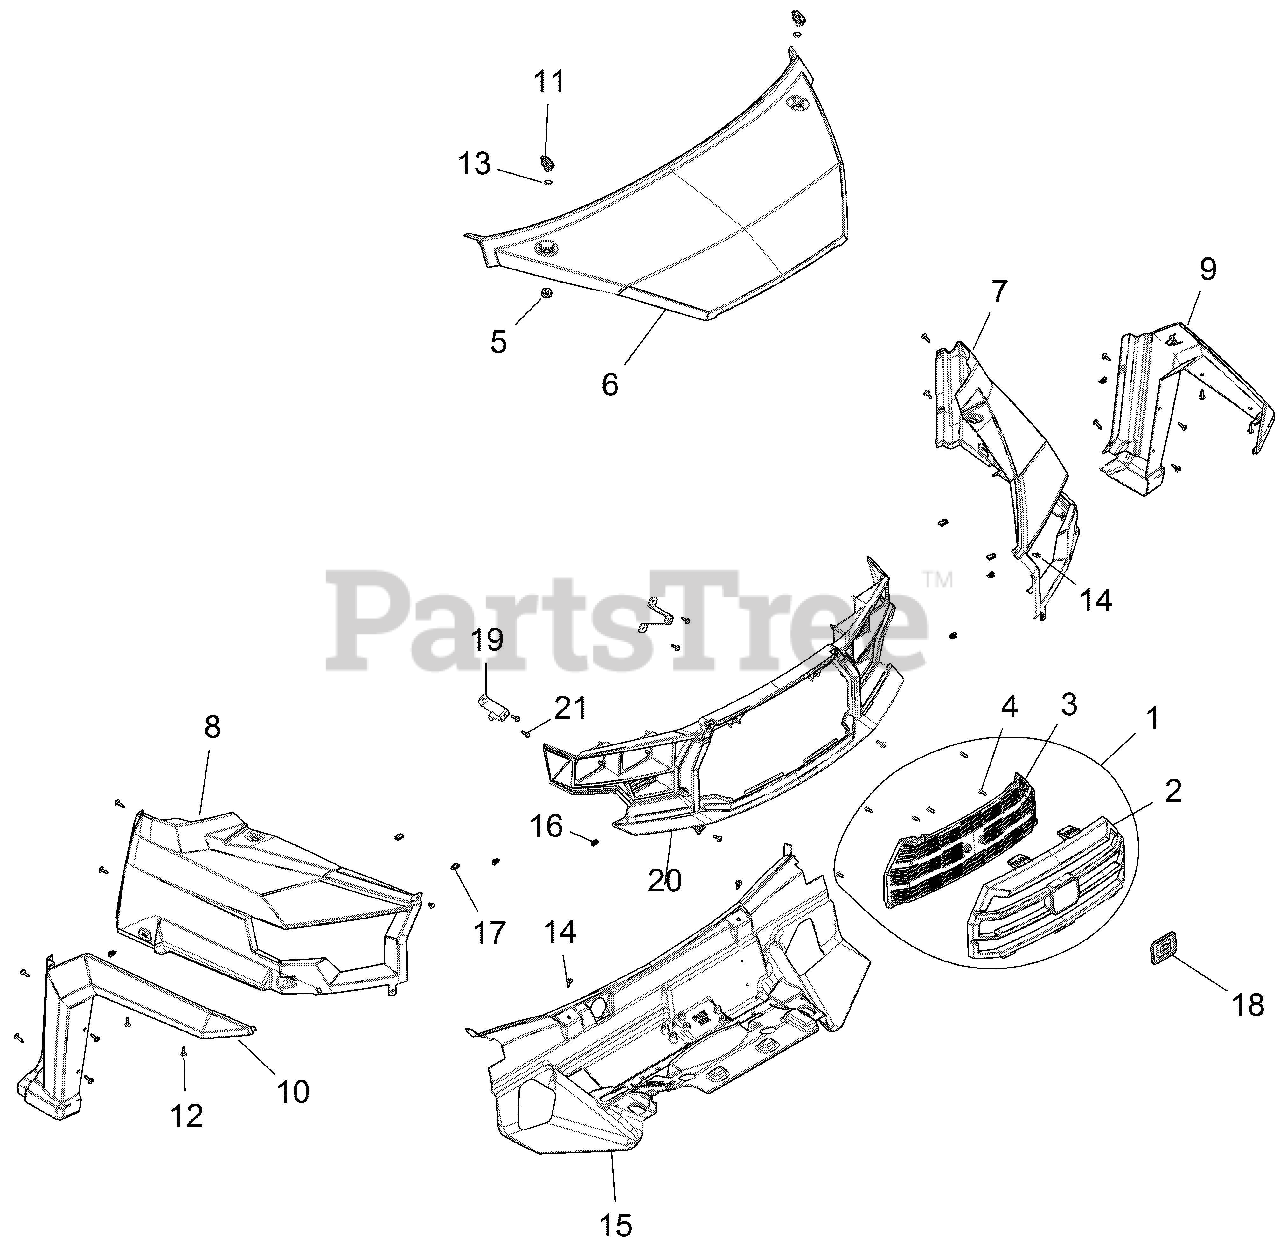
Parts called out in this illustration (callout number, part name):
1	ASM., GRILL, GRAVELY
2	GRILL, FRONT, UPPER, BLACK
3	GRILL, UPPER, TRIM
4	SCR-TXPH-#14 X .75 HI-LO RIE
5	GROMMET-LATCH
6	HOOD-ARIENS,INDY RED
7	FENDER-FRONT,LH,ARIENS,I RED
8	FENDER-FRONT,RH,ARIENS,I RED
9	FLARE-FENDER,FRONT,LH,ARIENS
10	FLARE-FENDER,FRONT,RH,ARIENS
11	LATCH, 1/4 TURN
12	SCR-TXTH-M6X1.0X25 RIE
14	RIVET-TUFLOK,.315-.325X.787 (5
15	LINER-HOOD,BLK
16	CLIP, DASH TRIM METAL
17	CLIP-U SPEED NUT
19	BRKT-FASCIA MOUNT
20	BEZEL-HEADLIGHT
21	SCR-M6X1.0X20,HXHD,FLG,TDFM,BL
